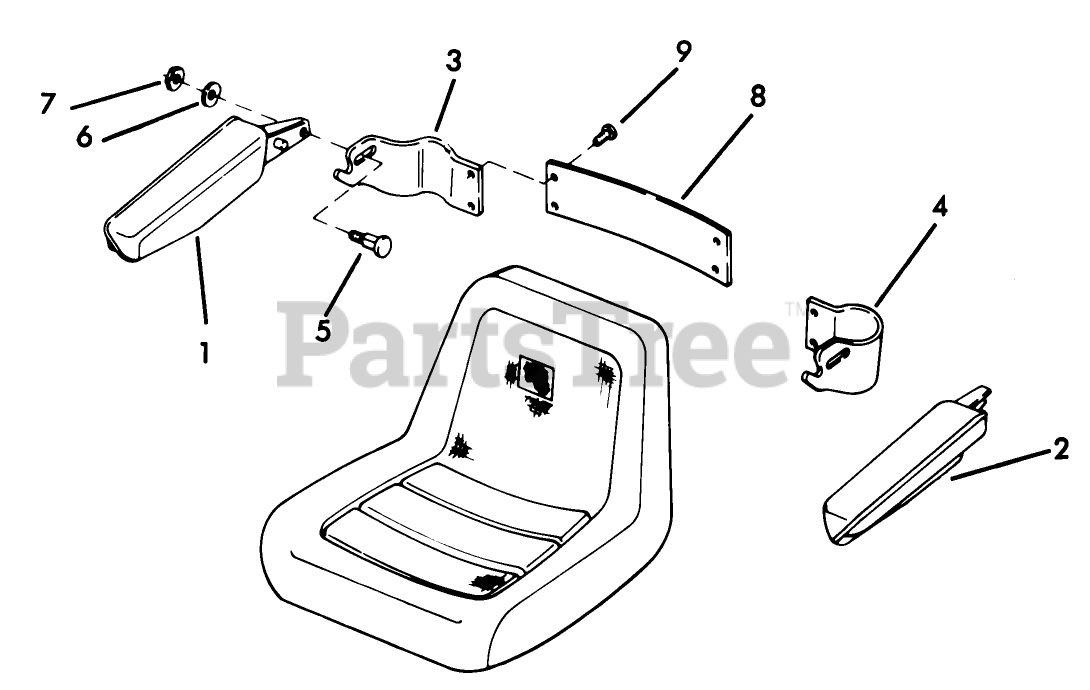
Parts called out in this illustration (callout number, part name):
1	Arm R.H.
2	Arm L.H.
3	Bracket R.H.
4	Bracket L.H.
5	Bolt (Slide Pivot)
6	Washer, Bellville
7	Nut (Pivot)
8	Bracket-Arm Brace
9	Screw
